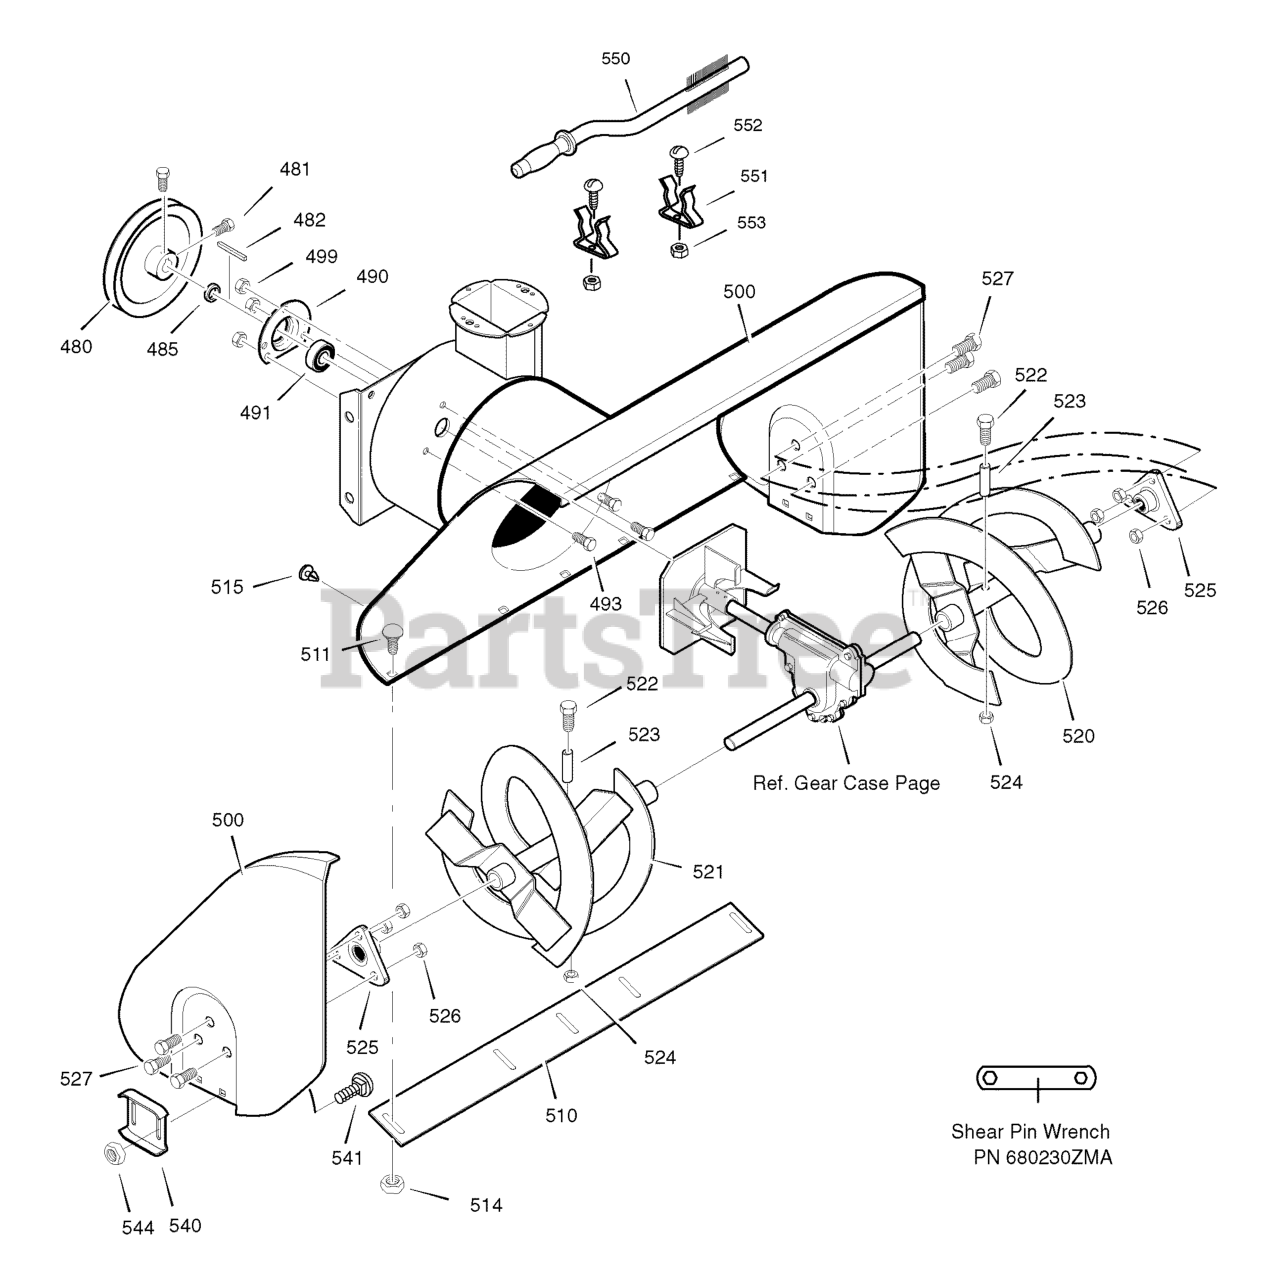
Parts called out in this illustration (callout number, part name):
480	PULLEY, 4L 6.12 X .67
481	SCREW, 5/16-18 x 0.63
482	KEY, SQUARE 3/16 X 3/4
485	SPACER, FRICTION PULLEY
490	RETAINER, BALL BEARING
491	BEARING, BALL
493	BOLT, HEX 5/16-18 X .62
499	NUT, 5/16-18 HEXWDFLLK
500	HOUSING, ASSEMBLY
510	BLADE, SCRAPER 24"
511	BOLT, Carriage, 1/4 x 3/4, G5
514	NUT, 1/4-20
515	FASTENER, RATCHET
520	AUGER, ASSEMBLY, LH
521	AUGER, ASSEMBLY, RH
522	SCREW, 1/4-20 X 1.75
523	SPACER, SLEEVE
524	NUT, 1/4-20
525	BEARING, FLANGE
526	NUT, 5/16-18
527	SCREW, 5/16-18 x 0.75
540	SKID, HEIGHT ADJUST
541	BOLT, 5/16-18 X .50
544	NUT, 5/16-18
550	BRUSH, CLEANOUT
551	CLAMP, SPRING
552	SCREW
553	NUT
